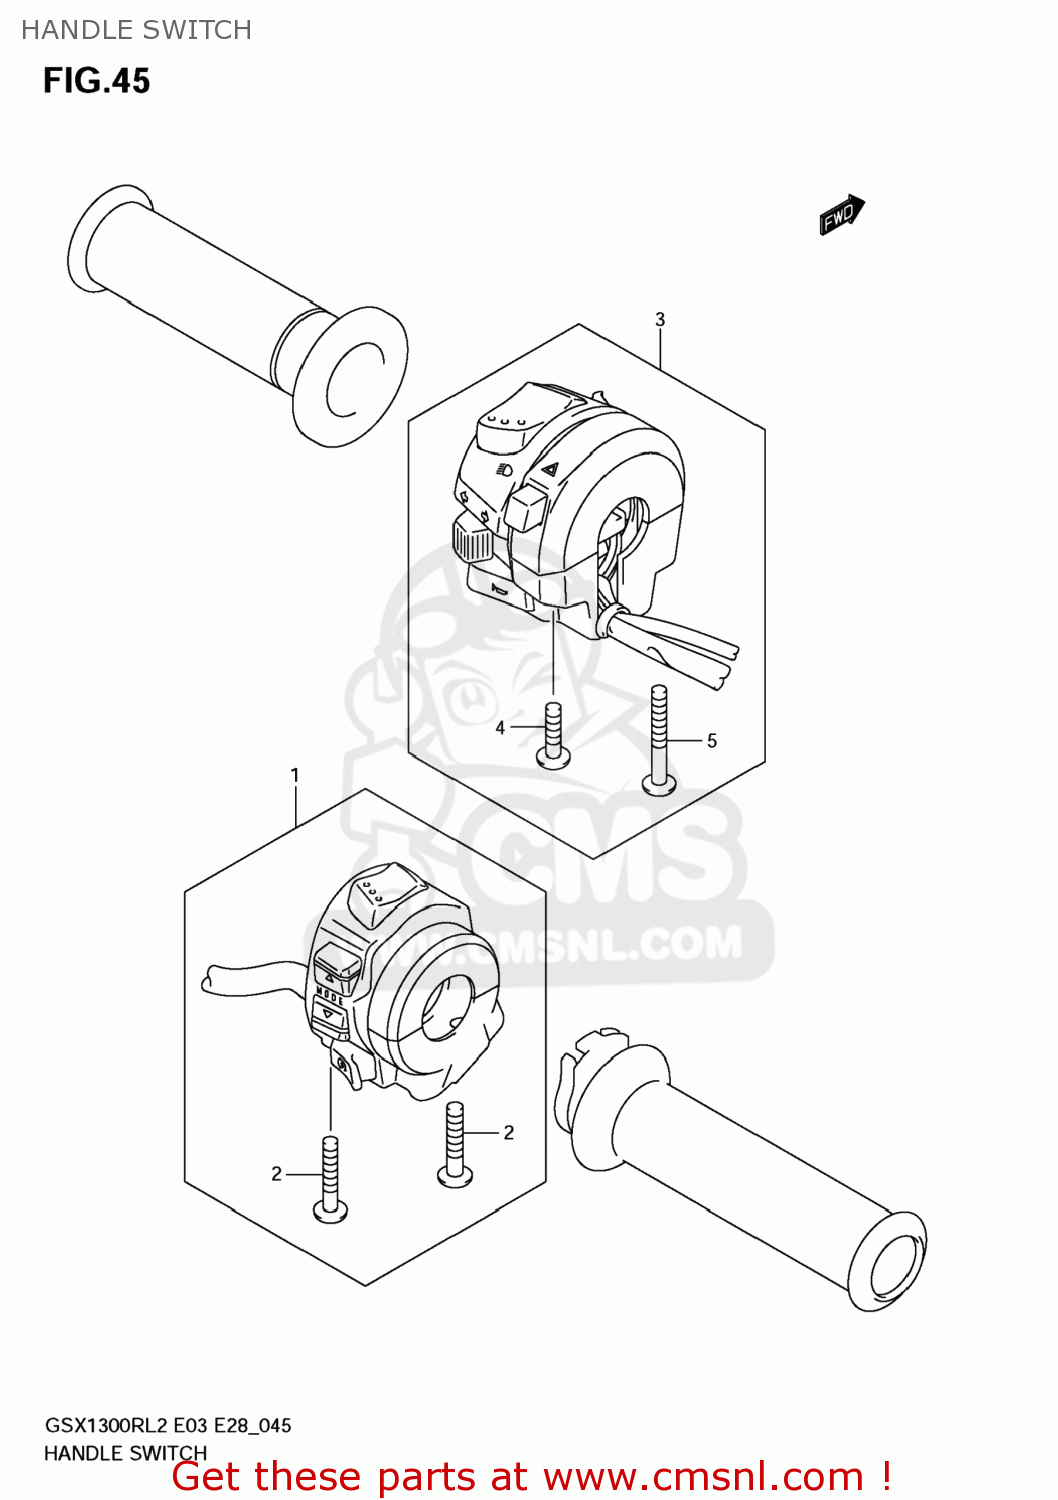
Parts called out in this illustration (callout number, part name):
1	SWITCH ASSY,HANDLE,R
2	SCREW
3	SWITCH ASSY,HANDLE,L
4	SCREW
5	SCREW
